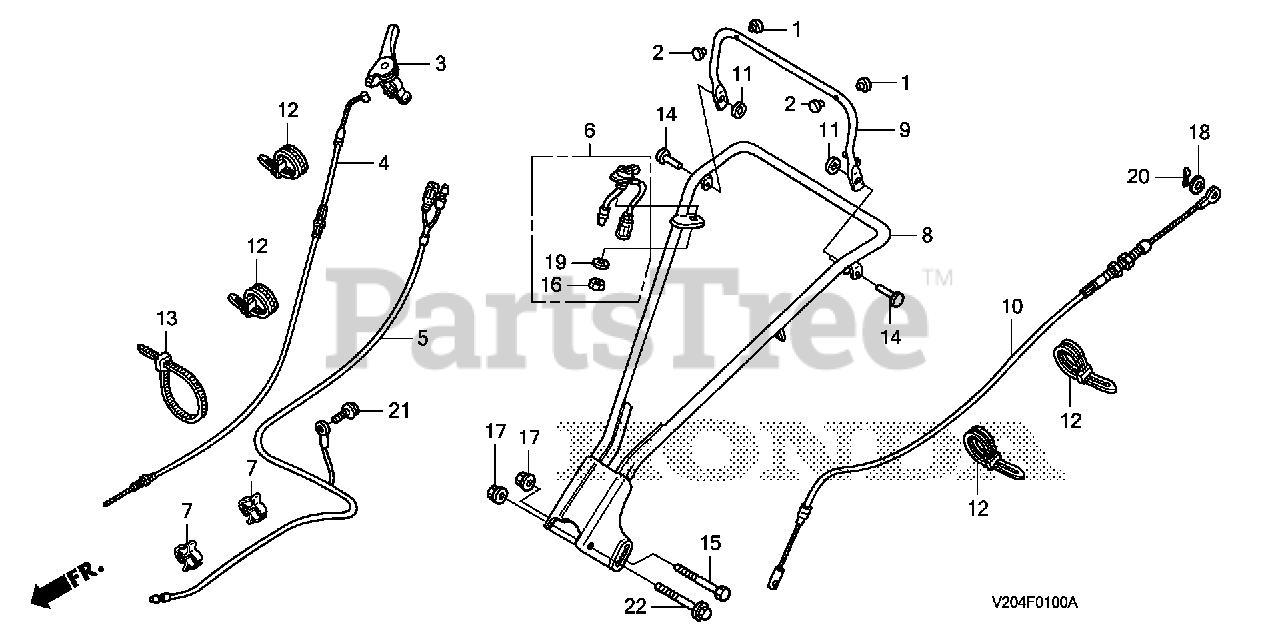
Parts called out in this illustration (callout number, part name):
3	LEVER ASSY., THROTTLE (COO)
4	CABLE, THROTTLE
5	WIRE, STOP SWITCH
6	SWITCH ASSY., ENGINE STOP
7	HOLDER, STOP SWITCH WIRE Use up to Engine SN 2056819.
8	PIPE, HANDLE *NH105* (MAT BLACK)
9	LEVER, CLUTCH *NH105* (MAT BLACK)
10	CABLE, CLUTCH
11	WASHER, SPECIAL (8MM)
12	BAND, WIRE HARNESS
13	BAND, WIRE HARNESS
14	PIN, CLUTCH LEVER
15	BOLT, HEX. (10X150)
16	NUT, HEX. (8MM) (NOT AVAILABLE)
17	NUT, FLANGE (10MM)
18	WASHER, PLAIN (6MM)
19	WASHER, SPRING (8MM)
20	PIN, SPLIT (2.0)
21	BOLT, FLANGE (8X12)
22	BOLT, FLANGE (10X150)
